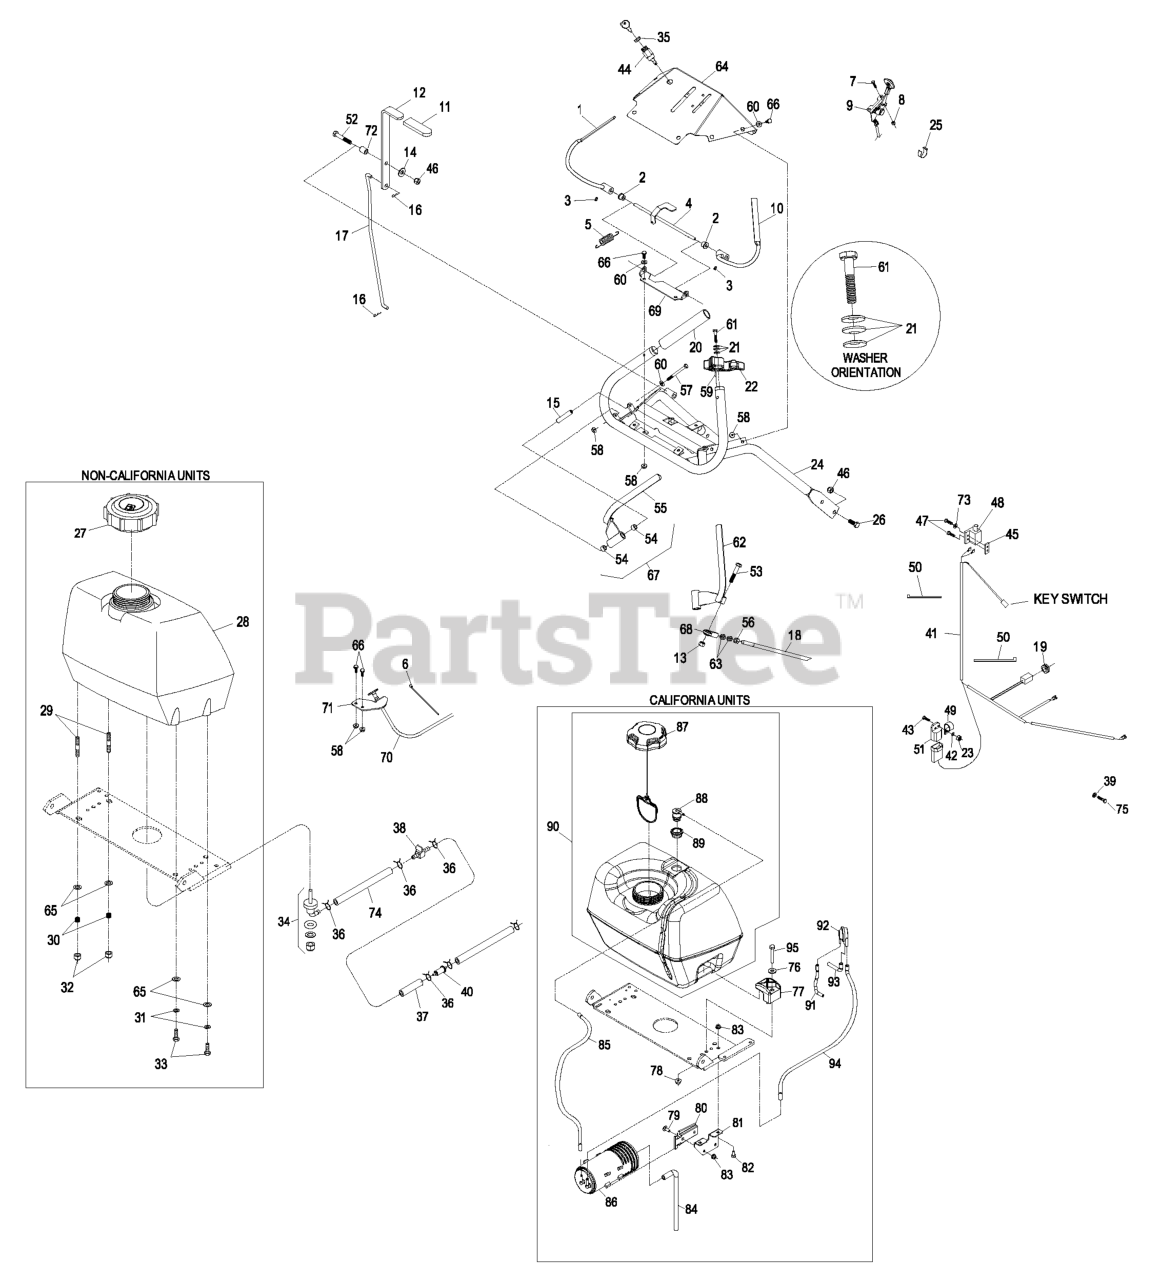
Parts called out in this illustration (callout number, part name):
2	BUSHING-NYLON
3	SCREW-SET
4	WLD,OPC LEVER AXLE
5	SPRING-EXTENSION
6	TIE-PLASTIC
7	BOLT-CARR
8	NUT-LOCK, NI
9	CONTROL, THROTTLE
11	GRIP-LEVER
12	CLUTCH LEVER-W/GRIP
13	NUT-LOCK, NI
14	WASHER-FLAT
15	BUSHING-LEVER, DRIVE
16	PIN-COTTER
17	LINKAGE,UPPER BLADE (PLT)
18	LINKAGE,DRIVE (PLT)
19	GROMMET
20	GRIP-BAR, HANDLE
21	WASHER-SPRING
23	NUT-LOCK, NI
24	WLD,UPPER ECS HANDLE
25	CLIP-CABLE
26	SCREW-HH
27	CAP-FUEL, GAS
28	ASM,FUEL TANK W/B
29	STUD
30	SPRING-TANK, FUEL
31	WASHER-LOCK
32	NUT-LOCK, NI
33	SCREW-HH
34	FITTING-FUEL, BULKHEAD
35	NUT-SWITCH, IGNITION
37	HOSE-FUEL
38	VALVE-FUEL
39	WASHER-PLAIN
40	Pn 41019-1055 W/6" Fuel Line
41	HARNESS-WIRE
42	WASHER-FLAT
43	SCREW-HH
44	SWITCH & KEY (INCLUDES NU
45	PLATE-TAPPED
46	NUT-LOCK, NI
47	SCREW-PPH
48	SWITCH-OPEN, NORMALLY
49	CLIP-LOOM
50	TIE-CABLE
51	MODULE-INTERLOCK
52	SCREW-CARR
53	SCREW-HH
54	BUSHING-SLEEVE
56	NUT-HEX
57	SCREW-HH
60	WASHER-FLAT
61	SCREW-HH
63	NUT-HJ
64	ASM, CONSOLE W/DECALS
65	WASHER-PLAIN
66	SCREW-HH
67	DRIVE LEVER-ASM, RH
68	JOINT-BALL, END
69	BRACKET,OPC AXLE
70	CABLE-CHOKE
71	BRACKET-CABLE, CHOKE
72	BUSHING-LEVER, LIFT
73	WASHER-FLAT
74	HOSE-FUEL
75	SCREW-HH
76	WASHER-FLAT
78	NUT-HF, NI
79	SCREW-HH
80	BRACKET-CANISTER, CARBON
81	BRACKET-CANISTER, CARBON
82	BOLT-CARR
84	HOSE-VENT, CANISTER
85	HOSE-VENT
86	CANISTER-CARBON, 800CC
91	HOSE-VENT, FORMED
92	VALVE-CONTROL, VACUUM
93	HOSE-VENT, FORMED
94	HOSE-VENT, FORMED
95	SCREW-HH
